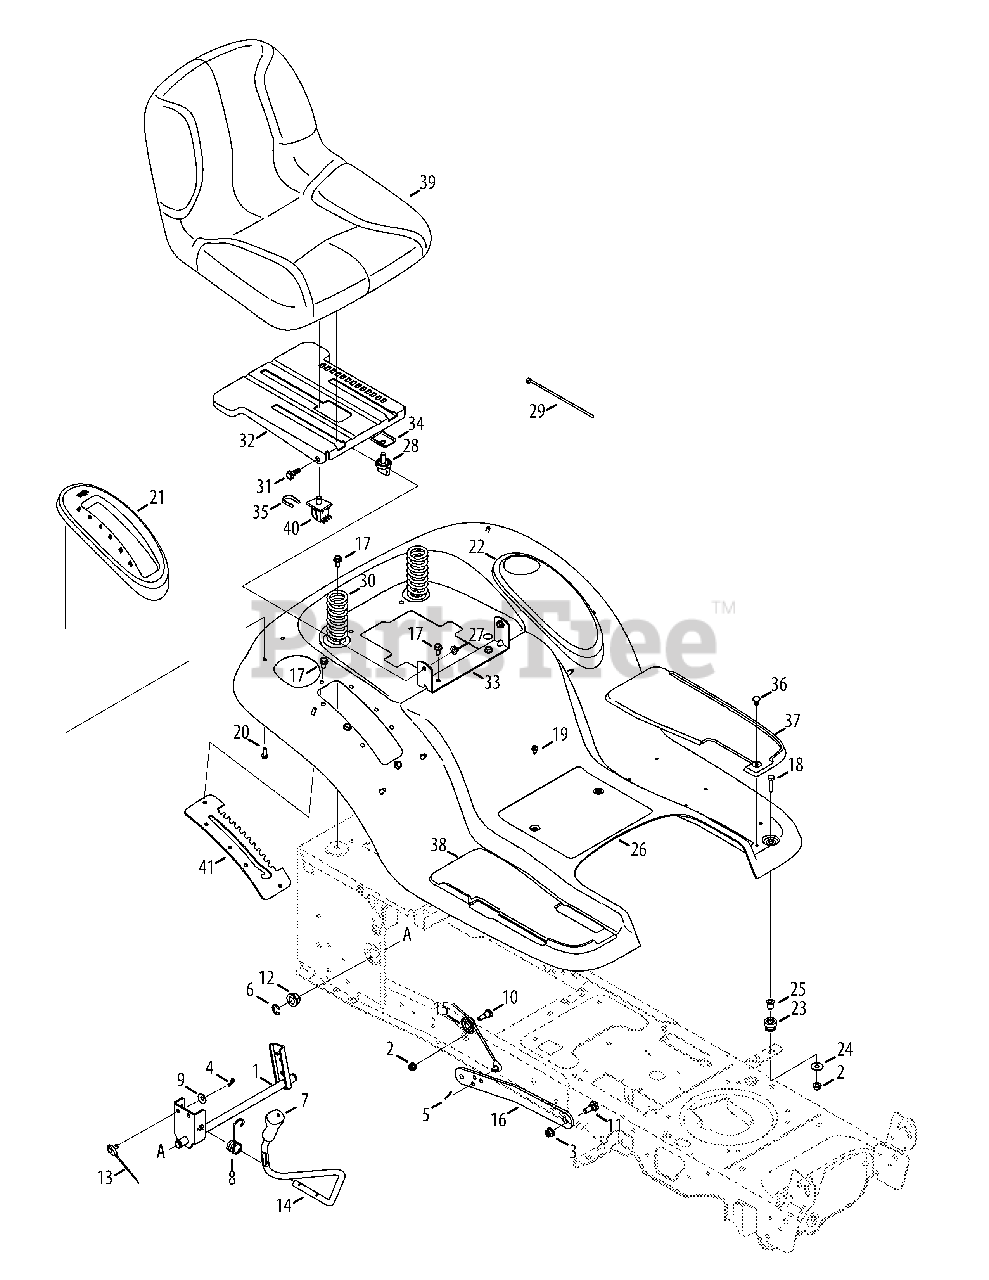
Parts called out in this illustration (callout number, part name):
1	Shaft Ass’y, Lift
2	Nut, Flange Lock, 5/16-18, Grf
3	Nut, Flange Lock, 3/8-16, Grf
4	Pin, Cotter, .072 Dia. x 1.13
5	Pin, Cotter, Bow-Tie 72
6	Ring, E Type, .625 Dia. Shaft
7	Grip, Handle, 1/2
8	Spring, Torsion
9	Washer, Spring, .401 x .870 x .063
10	Screw, Shoulder, .437 x .470, 5/16-18
11	Bolt, Shoulder, .500, 3/8-16
12	Bearing, Hex Flange
13	Cable, Lift, 16.16
14	Handle, Lift,
15	Pulley, Roller, Cable
17	Screw, Self-tapping, 5/16-18, .750,
18	Hex Screw, 5/16-18, 1.25, Gr5, Std
19	Screw, Self-tapping, 1/4-20, 0.500,
20	Screw, HL, 1/4-15, 0.750,
21	Cover, Lift Lever
22	Cover w/ Cup Holder
23	Grommet, .4375 ID x .750
24	Washer, Flat .344 x 1.00 x .063
25	Spacer, Flange, .3125 x .4375 x .625
27	Nut, Flange Lock, 5/16-18, Gr5, Sd Lk
28	Knob, 3/8-16, .875
29	Cable, Tie, 3/16 x .05 x 7.4
30	Spring, Comprs, 1.50 x 3.90 x .200
31	Screw, Shoulder, .437 x .268, 5/16-18
32	Bracket, Mounting, Seat
33	Bracket, Pivot, Seat
34	Bracket, Knob Adjustment, Seat
35	Clip, Retaining, Switch
36	Clip, Ratchet, .250 Dia
37	Pad, Foot, LH
38	Pad, Foot, RH
39	Seat, Medium Back
40	Switch, Seat
41	Bracket, Lift, Man PTO, 6 Pos
